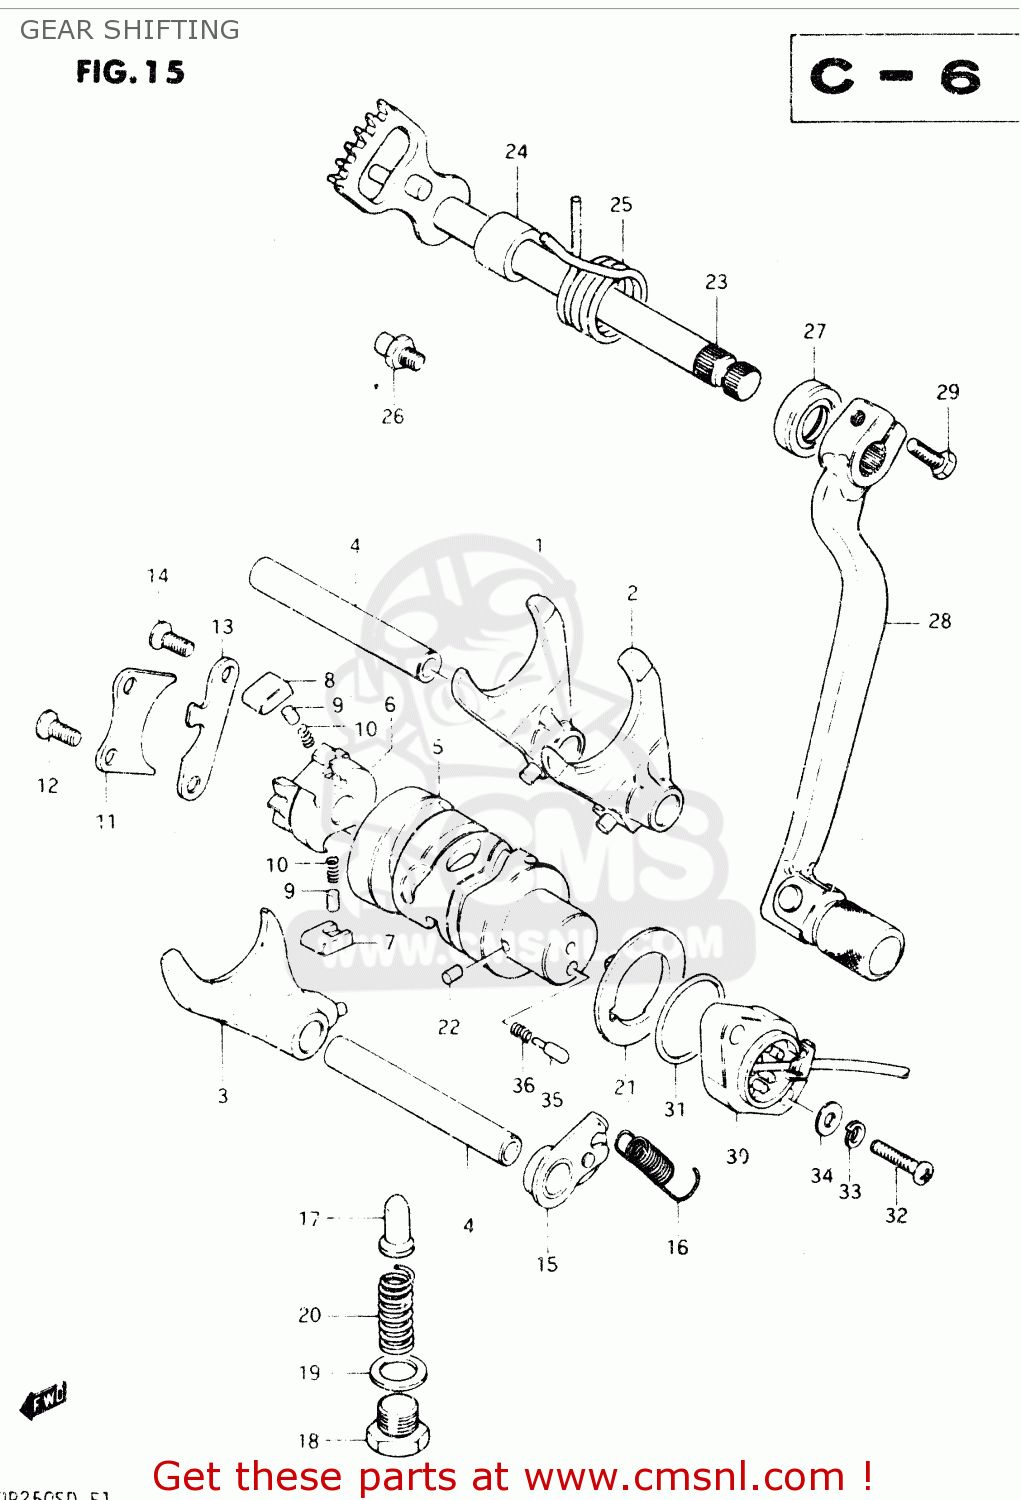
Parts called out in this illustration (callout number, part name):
1	FORK,GEAR SHIFT NO.1
2	FORK,GEAR SHIFT
3	FORK,GEAR SHIFT NO.3
4	SHAFT,GEAR SHIFT FORK
5	CAM,GEAR SHIFT
6	SHIFTER,GEAR SHIFT CAM
7	PAWL,GEAR SHIFT NO.1
8	PAWL,GEAR SHIFT NO.2
9	PIN(5X8)
10	SPRING
11	LIFTER,GEAR SHIFT PAWL
12	SCREW
13	GUIDE,GEAR SHIFT CAM
14	SCREW
15	STOPPER,GEAR SHIFT CAM
16	SPRING
17	STOPPER,GEAR SHIFT CAM NO.2
18	PLUG (14X12)
19	GASKET(14X19.2X2) (NAS)
20	SPRING
21	PLATE,GEAR SHIFT CAM STOPPER
22	PIN 4X6
23	SHAFT,GEAR SHIFT
24	SPACER(12X20X15.3)
25	SPRING
26	STOPPER,GEAR SHIFT CAM
27	OIL SEAL
28	LEVER ASSY,GEAR SHIFT
29	BOLT
30	TERMINAL BASE,NEUTRAL SWITCH
31	O-RING (D:2.4 ID:26.2)
32	SCREW 5X20
33	LOCK WASHER
34	WASHER
35	PIN(5X15.5)
36	SPRING
